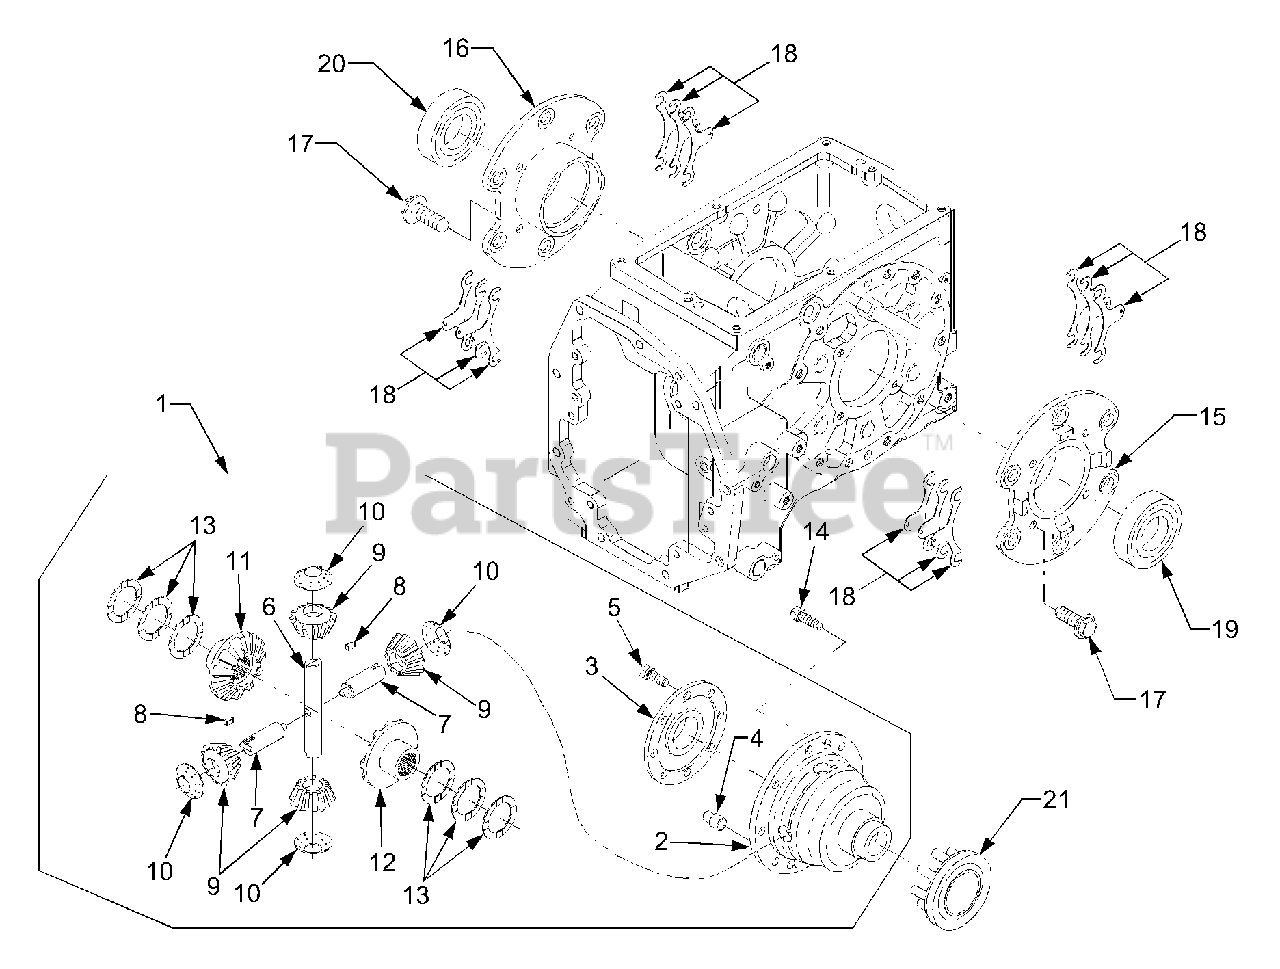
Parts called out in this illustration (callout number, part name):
1	Differential System
2	Case, Differential System
4	Pin, Straight
6	Shaft, 1 Differential Pinion
7	Shaft, 2 Differential Pinion
9	Pinion, Differential
10	Washer, Differential Pinion
11	Gear, Differential Side (RH)
12	Gear, Differential Side (LH)
13	Washer, Differential (1.7)
13	Washer, Differential (1.5)
13	Washer, Differential (1.6)
15	Case, Differential Bearing (LH)
16	Case, Differential Bearing (RH)
19	Bearing, Taper Roller
20	Bearing, Taper Roller
21	Shift, Differential Lock
